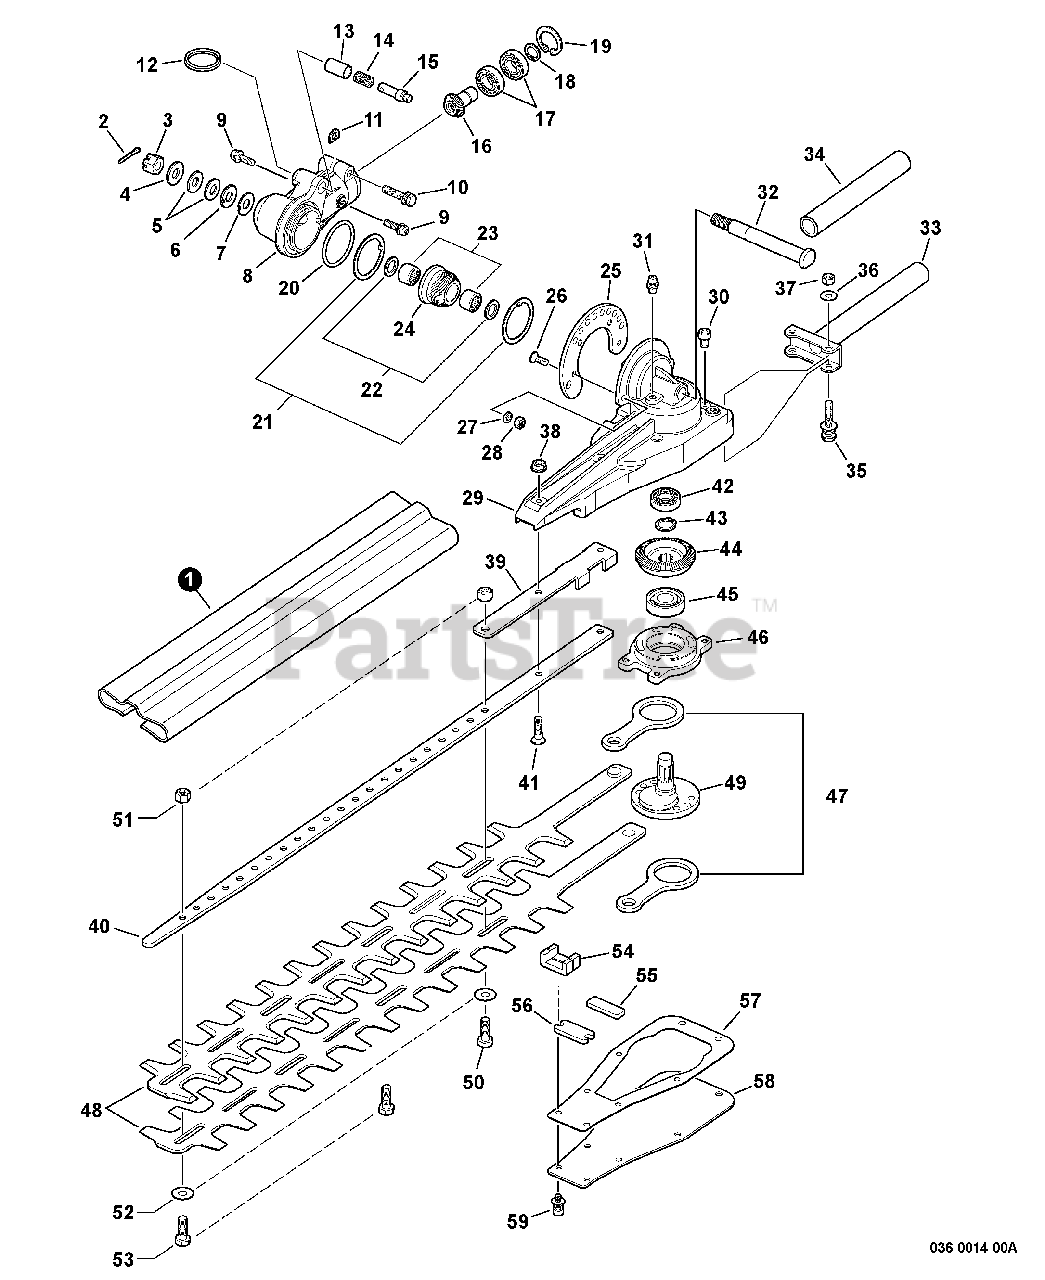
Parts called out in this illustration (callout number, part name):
1	SCABBARD
2	PIN, COTTER 6×18
4	WASHER 8
5	WASHER, CONICAL
7	GASKET, GEAR CASE
8	CASE, GEAR
9	SCREW 5×12
10	BOLT 5×25
12	RING, RETAINING
13	COLLAR 8
14	SPRING, COMPRESSION
15	LINCHPIN
16	GEAR, BEVEL
17	BEARING, BALL 6900
18	RING, SNAP
19	RING, SNAP Ø22
20	O-RING 32
22	WASHER 10
23	BEARING, NEEDLE 10
24	GEAR, BEVEL
25	LATCH, RESETTER
26	SCREW 4×12
27	WASHER, SPRING 4 MM
28	NUT, LOCK 4
29	CASE, GEAR
30	BOLT 5×8
31	FITTING, GREASE
32	SHAFT, GEAR
33	ADJUSTOR ASSY, HANDLE
34	GRIP, HANDLE
35	BOLT 5×28
36	WASHER, FLAT 5.5×10×0.8
37	NUT, LOCK M5
38	NUT, FLANGE M5
39	GUIDE, BLADE
40	SUPPORT, BLADE
41	SCREW 5×20
42	BEARING, BALL 6900
43	RING, SNAP 11
44	GEAR, BEVEL
45	BEARING, BALL 6001
46	HOLDER, BEARING
47	ROD, CONNECTING
50	BOLT, CUTTER
52	WASHER 6.5×15.5×0.6
53	BOLT 6×18
55	GUIDE, BLADE
56	GUIDE, BLADE
57	GASKET, GEAR CASE
58	COVER, GEAR CASE
59	BOLT 4×12
